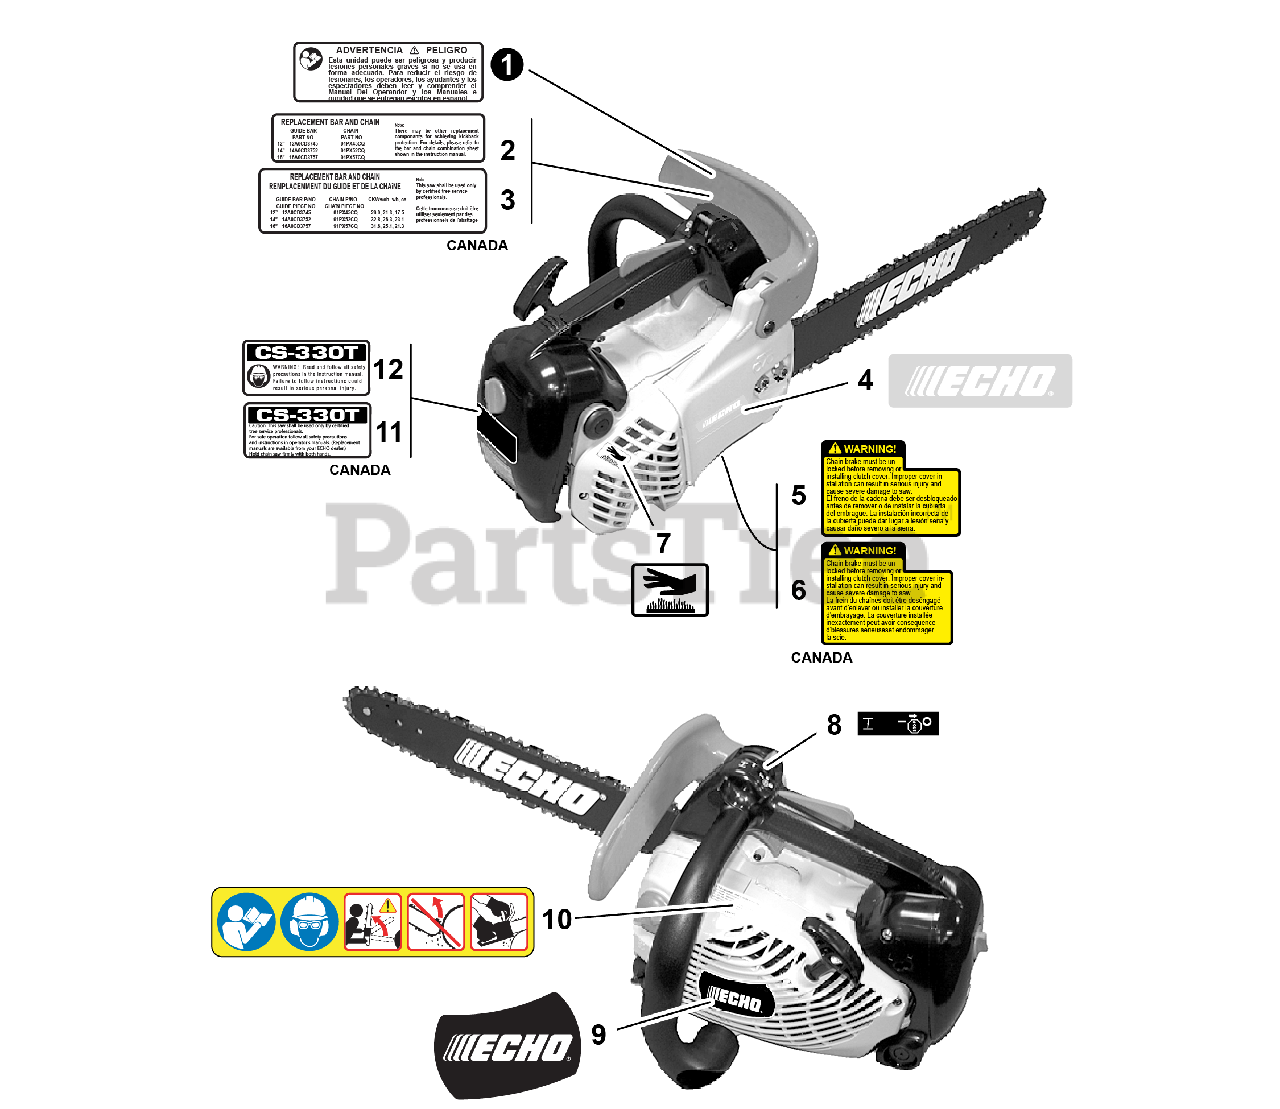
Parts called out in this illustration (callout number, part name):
1	LABEL, CAUTION
2	LABEL, BAR & CHAIN
3	LABEL, BAR & CHAIN
4	LABEL, ECHO
5	LABEL, WARNING
6	LABEL, WARNING
7	LABEL, CAUTION - HOT
9	LABEL, ECHO
10	LABEL, CAUTION
11	LABEL, MODEL
12	LABEL, MODEL
